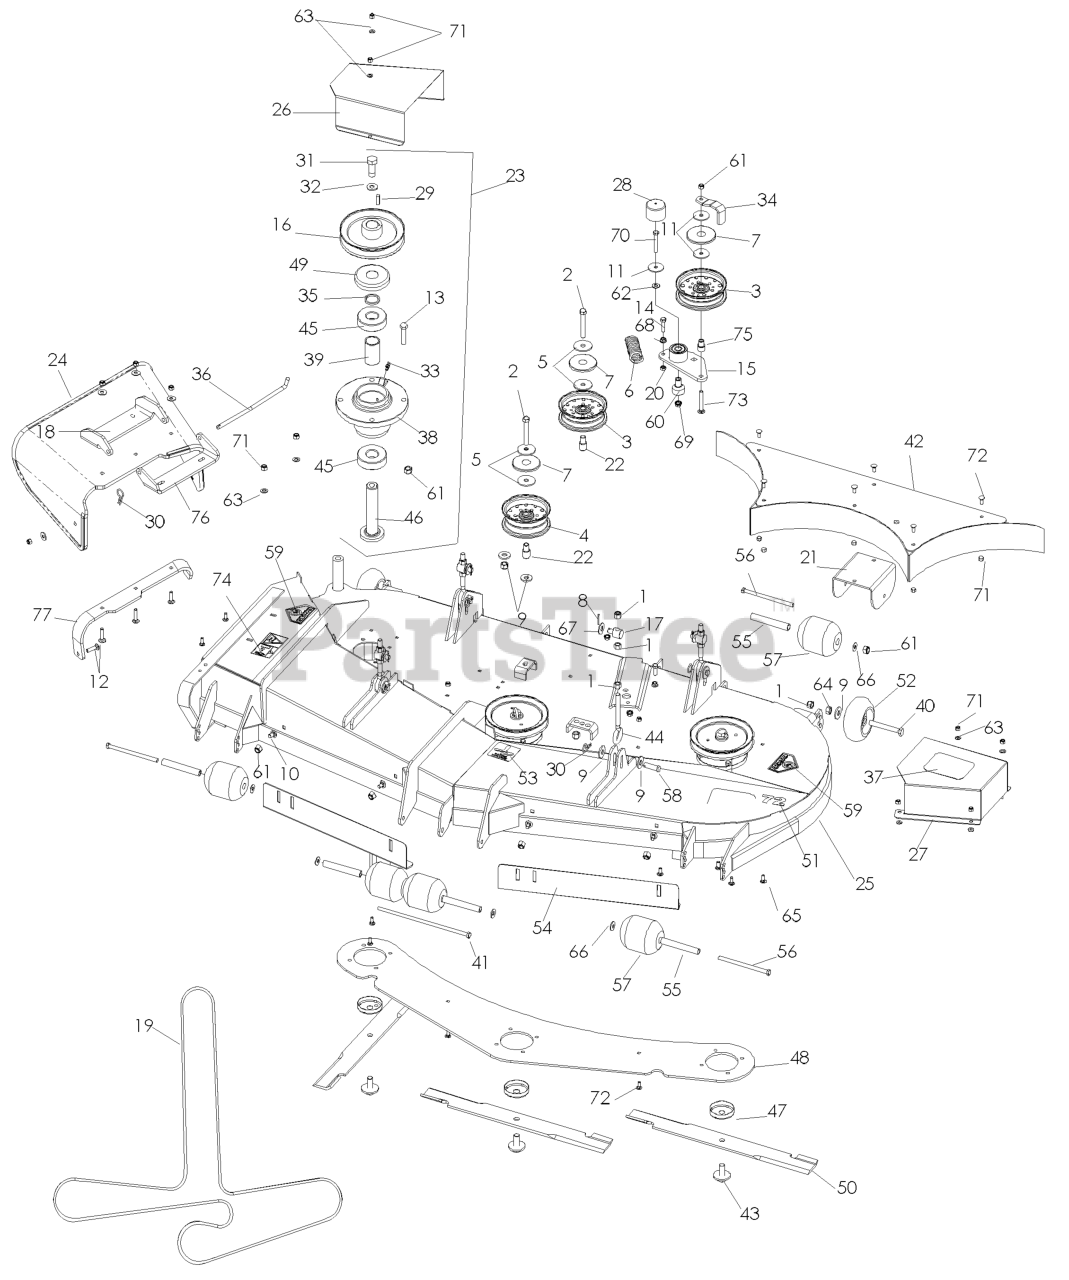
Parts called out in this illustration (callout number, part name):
1	NUT 1/2-13 HEX NYLOC ZD
2	SCREW, 1/2C X 3 HEX CAP
3	IDLER PULLEY
4	IDLER PULLEY (TALL)
5	ISOLATOR WASHER
6	DECK SPRING
7	TOP DUST CAP
8	PIN COTTER 1/8 X 1 ZD
9	WASH USS FLAT 1/2
10	RHSNB 3/8-16 X 3/4 GR5 ZD
11	WASHER, 3/8 SPEC
12	RHSNB 5/16-18 X 1-1/2 GR 5 ZD
13	HCS 3/8C X 1 1/2
14	HCS 3/8-16 X 1-1/2
15	ARM-IDLER W/BRG
16	PULLEY, 7.50 O.D.
18	PIVOT BRKT RUBBER CHUTE
19	BELT-DECK, 72
20	NUT 3/8-16 HEX JAM
21	REAR CENTER ROLLER BKT 72 BLK
22	SPACER - IDLER
23	SPINDLE ASSEMBLY, 72
24	CHUTE, RUBBER DISCHARGE 72"
25	DECK W/DECAL 72 GRIZZLY
26	PULLEY GUARD 72, RH PAINTED
27	PULLEY GUARD 72, LH PAINTED
28	CAP, VINYL
29	KEY - 1/4 X .88
30	PIN, COTTER 1 3/4
31	1/2-20 UNF X 1 1/4 HHBLT
32	WASHER .525 X 1.375 X .25
33	ZERK, 3/16, DRIVE IN
34	GUIDE, BELT
35	SPACER .25
36	DEFLECTOR PIN
37	REAR FLOOR PAD-LH
38	DECK HUB MACHINED
40	HCS 1/2-13 X 4 GR 5 ZD
41	3/8-16X12 HHB G5
42	W-BAFFLE WLDT
43	BLADE BOLT/WASHER
44	BOLT, EYE
45	BEARING - 6305 - 2RS
46	SHAFT SHORT
47	TRASH GUARD
48	HUB STIFFENER PLATE
49	TRASH GUARD
50	BLD 72" HI LIFT FUS
51	DECAL, 72"
52	GAUGE WHEEL
53	DECAL, BELT ROUTING (18656)
54	BLOW BY BAFFLE
55	BUSHING
56	3/8-16 X 6-1/2 HHB GR8
57	ROLLER 3-3/4 DIA. X 4-1
58	CLEVIS PIN 1/2X1-3/4LG
59	DECAL, CPSC
60	PIVOT, BEARING
61	NUT 3/8-16 NYLOC
62	WASHER 3/8 SAE FLAT
63	FLAT WASHER 5/16 SAE
64	NUT HEX 1/2
65	BOLT 5/16C X 3/4" CARRIAGE
66	WASHER 3/8 FLAT
67	WASHER 1/2 FLAT
68	HCS 3/8C X 1
69	NUT 3/8C WHIZ
70	HCS 3/8C X 2 1/2
71	NUT 5/16 NYLOC
72	RHSSNB 5/16C X 1.0
73	RHSNB 3/8-16 X 2.75
74	DECAL, EURO SEVERING
75	BUSHING, IDLER
76	PIVOT BRACKET - DECK
77	BRKT, REINF-CHUTE 72"
